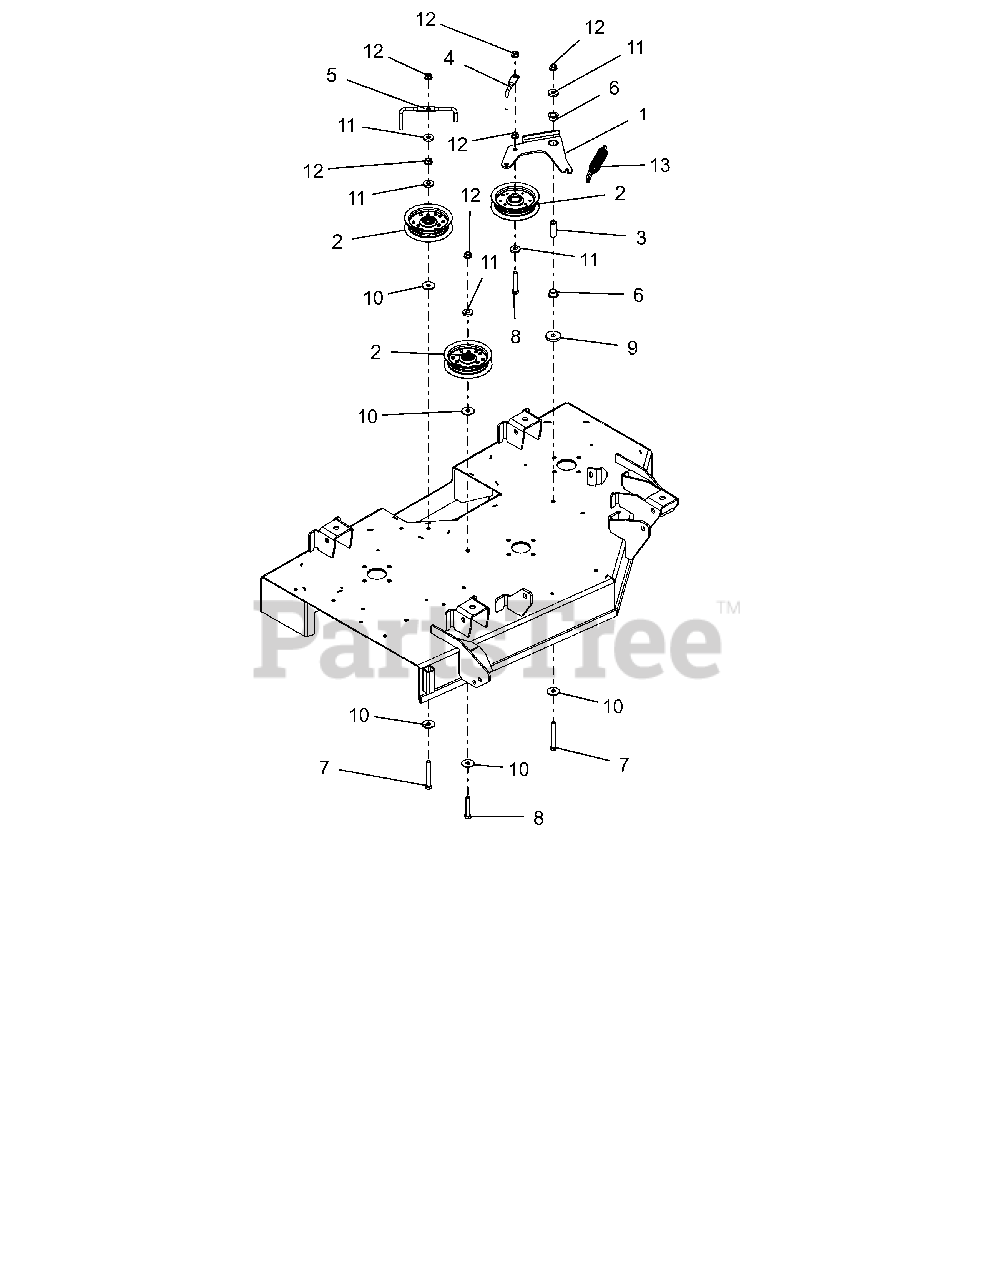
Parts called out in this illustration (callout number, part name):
1	WLDMT, IDLER ARM-42"
2	ASM, IDLER 4"
3	SPACER, .375IDX.625ODX1.66 PM
4	WIREFORM, BELT FINGER
5	WIREFORM, BELT FINGER
6	BSHG-FLG, .625X.750X.500X1.00
7	BLT-HEX .38-16X3.00 GR5 FTH YZ
8	@BLT-HEX .38-16X2.25 GR5 YWZC
9	WSHR,FLT STL.406X1.50X.245YWZC
10	WSHR FL STL .406X1.25X.10ZC120
11	WSHR-FL-STL .406X1.00X.188 YWZ
12	NUT-LK-TOP-FLG .38-16 ZC120
13	SG-TENS .135X.98X6.0 WLD 62
